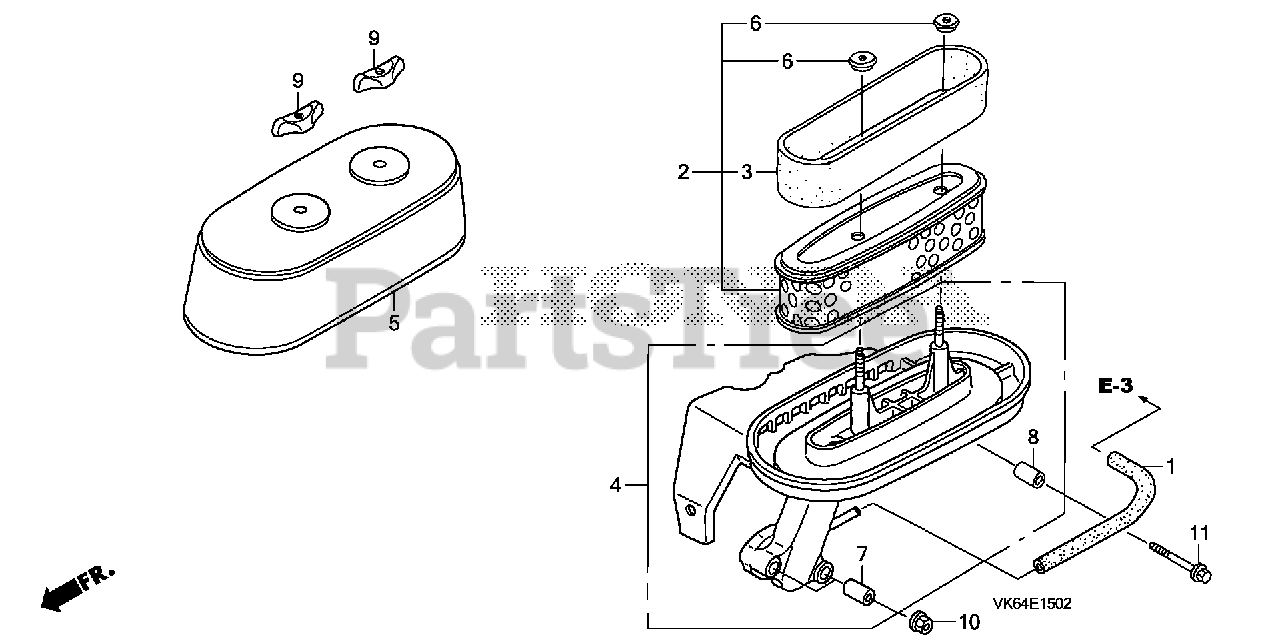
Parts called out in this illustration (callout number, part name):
1	TUBE, BREATHER
2	ELEMENT, AIR CLEANER
3	FILTER (OUTER)
4	HOUSING, AIR CLEANER
5	COVER, AIR CLEANER
6	GROMMET, AIR CLEANER
7	COLLAR, AIR CLEANER
8	COLLAR B, AIR CLEANER
9	NUT, AIR CLEANER
10	NUT, FLANGE (6MM)
11	BOLT, FLANGE (6X35)
